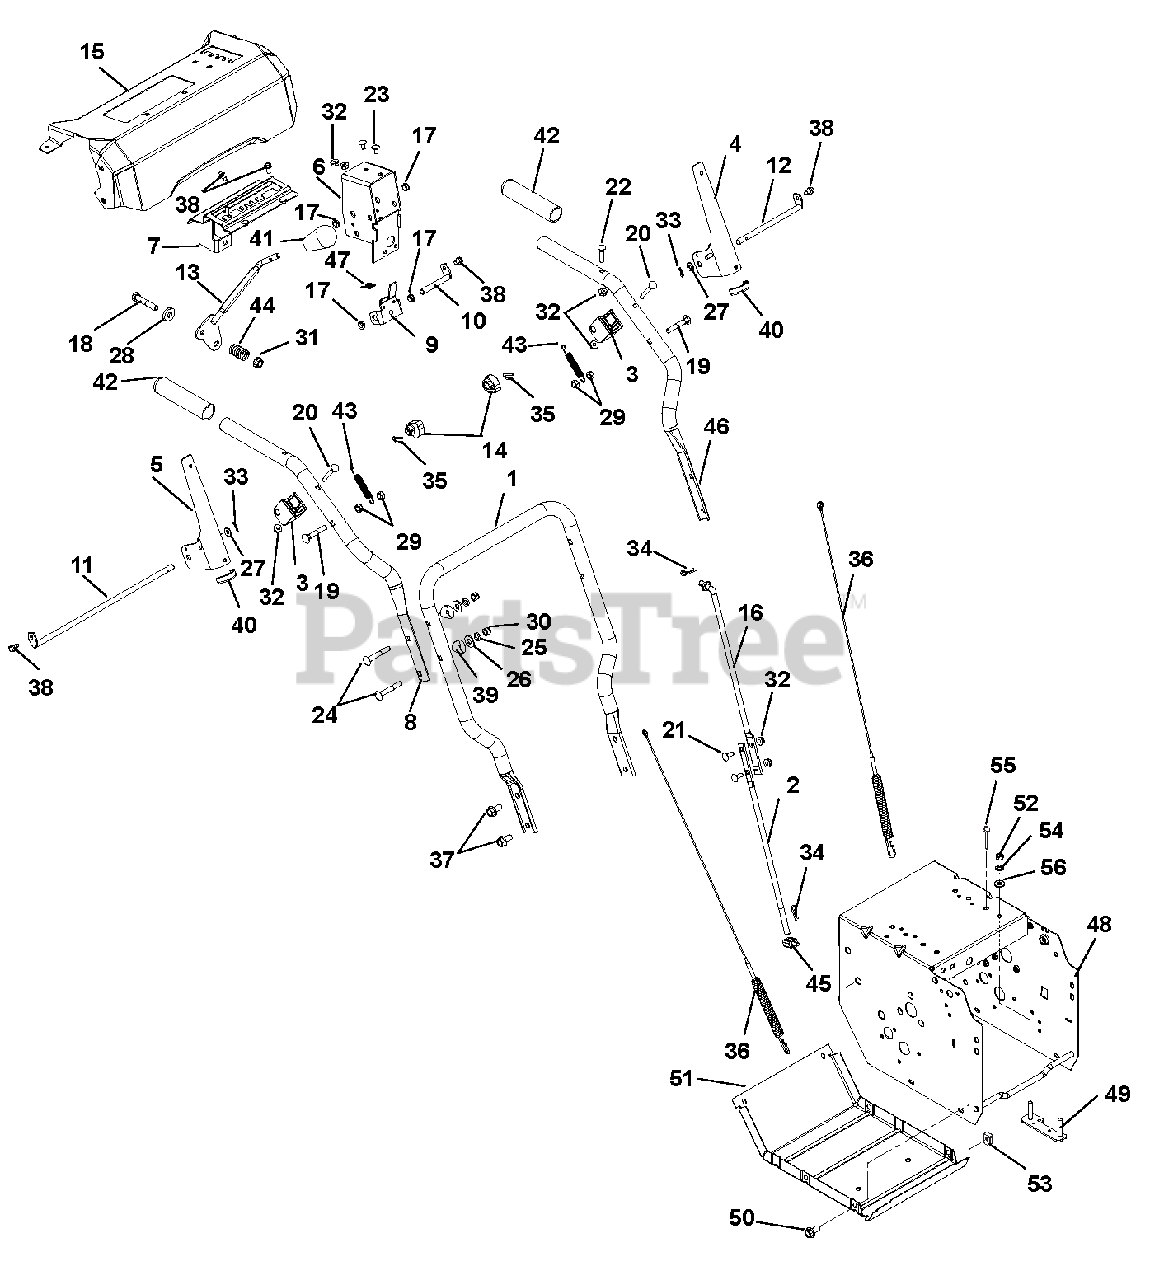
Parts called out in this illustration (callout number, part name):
1	HANDLEBAR, LOWER - DELUXE
2	ROD, SHIFT - LOWER
3	BLOCK, CLUTCH PADDLE
4	LEVER, CLUTCH-LH
5	LEVER, CLUTCH-RH
6	WELDMENT, BRACKET INTERLOCK
7	WELDMENT, DETENT PLATE-COMPACT
8	HANDLEBAR, UPPER - RH
9	BRACKET, INTERLOCK ARM
10	ROD, PIVOT - INTERLOCK
11	ROD, PADDLE MOUNT - LONG
12	ROD, PADDLE MOUNT - SHORT
13	LEVER, CONTROL-SHIFT(WELDMENT)
14	CAM, INTERLOCK
15	CONTROL PANEL W/DECAL, BRUSH
16	ROD, SHIFT - UPPER
17	BUSHING, POLYLINER-.38 SNAPIN
18	@BLT-HEX .38-16X2.00 GR5 YWZC
19	BLT-RDHDXLSQNK .31-18X2.0 G5YZ
20	BLT-RDHDXLSQNK .25-20X2.0 G5YZ
21	@BLT-RDHDSQNK .25-20X.75 G5YZ
22	BLT-RDHDXLSQNK.25-20X1.25 G5ZC
23	@BLT-RDHDSQNK .25-20X.50 G5YZ
24	@BLT-RDHDSQNK .31-18X2.25 G5YZ
25	WSHR-LK .312X.097 HVY YWZC
26	@WSHR-FL-STL.38X.875X.083 YWZC
27	@WSHR-FL-STL.281X.62X.065 YWZC
28	WSHR-FL-STL .406X1.00X.188 YWZ
29	@NUT-LK-CTR .31-18 YWZC
30	@NUT-LK-NYL .312-18 YWZC
31	@NUT-LK-TOP-FLG .38-16 YWZC
32	@NUT-LK-TOP-FLG .25-20 YWZC
33	PIN-HAIR INT .06X.18X.77
34	PIN-HAIR INT .08X.18X1.18 YWZC
35	PIN, SPRING CLIP
36	CABLE, AUGER (DELUXE & PRO)
37	BLT-SERHFWH .38-16X.75 YWZC
38	SCR-TAP .25-20X.50 HWH TR YWZ
39	SPACER, HANDLEBAR
40	EDGING, CLUTCH PADDLE - 2.00"
41	KNOB,SOFT TEARDROP,PUSH-ON BLK
42	HANDLE GRIP
43	SPRING, EXTENSION
44	SG-COMP .125X.781X1.250
45	PIVOT,SHIFT ROD .375-16(TRUNN)
46	HANDLEBAR, UPPER - LH
47	SPRING-EXT .047X.438X1.45
48	FRAME, 920/921
49	STRAP, ENGINE BOLT-WELDMENT
50	BLT-HEX .25-20X.75 HWH YZ GR5
51	COVER, BOTTOM
52	@NUT-HEX .31-18 YWZC
53	NUT-RTNR .25-20X.56
54	WSHR-LK .312X.097 HVY YWZC
55	RVT-POP .187 YZ
56	@WSHR-FL-STL.344X.688X.065YWZC
